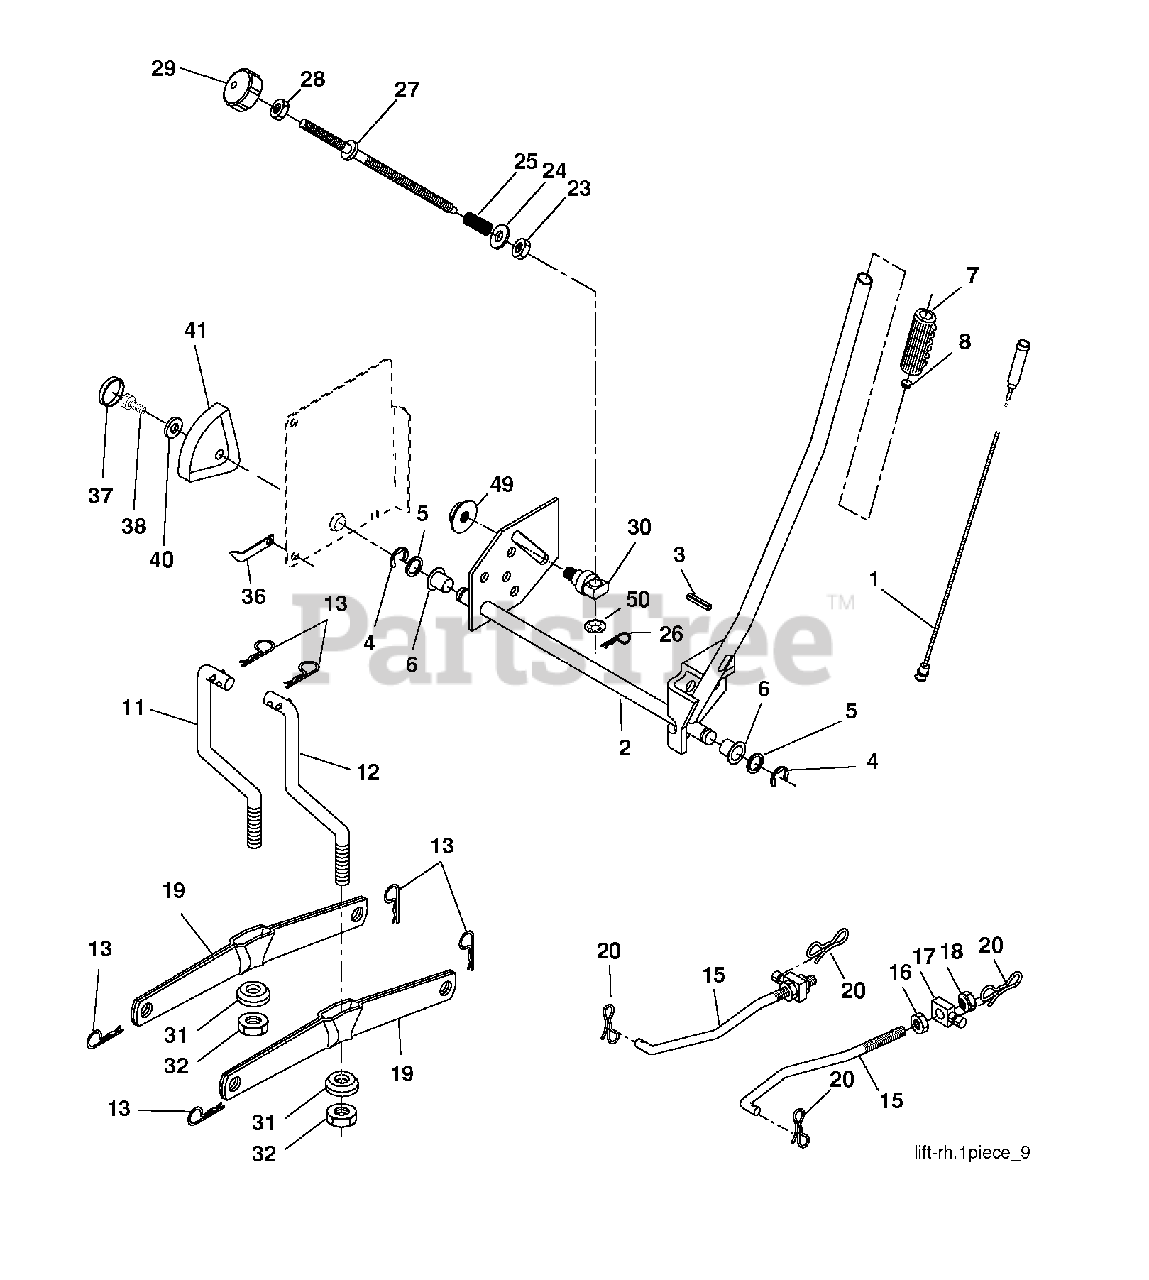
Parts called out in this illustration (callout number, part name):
1	PLUNGER.ASM.LIFT.LVR.BLK.17.32
2	SHAFT ASM R HANDLE
3	PIN GROOVE
4	RETAINING RING LT
6	BEARING.NYLON
7	GRIP HANDLE
8	PLUNGER BUT KIT
11	LINK
12	LINK
13	RETAINER-SPRNG RB
15	LINK.SUSPENSION.FRONT
16	NUT
18	NUT
19	ARM.REAR.SUSPENSION
20	PIN.COTTER.7/16.BOW TI
25	SPRING**
26	RETAINER CLIP
27	ROD ADJ LIFT
28	NUT
29	KNOB INF 3/8-16
31	BEARING.PIVOT.LIFT
32	NUT CROWNLOCK 3/8-24
36	POINTER, HEIGHT INDICATOR
37	PLUG,HOLE
38	SCREW 5/16-18X1
41	HEIGHT INDICATOR
49	NUT
50	NUT PUSH M
